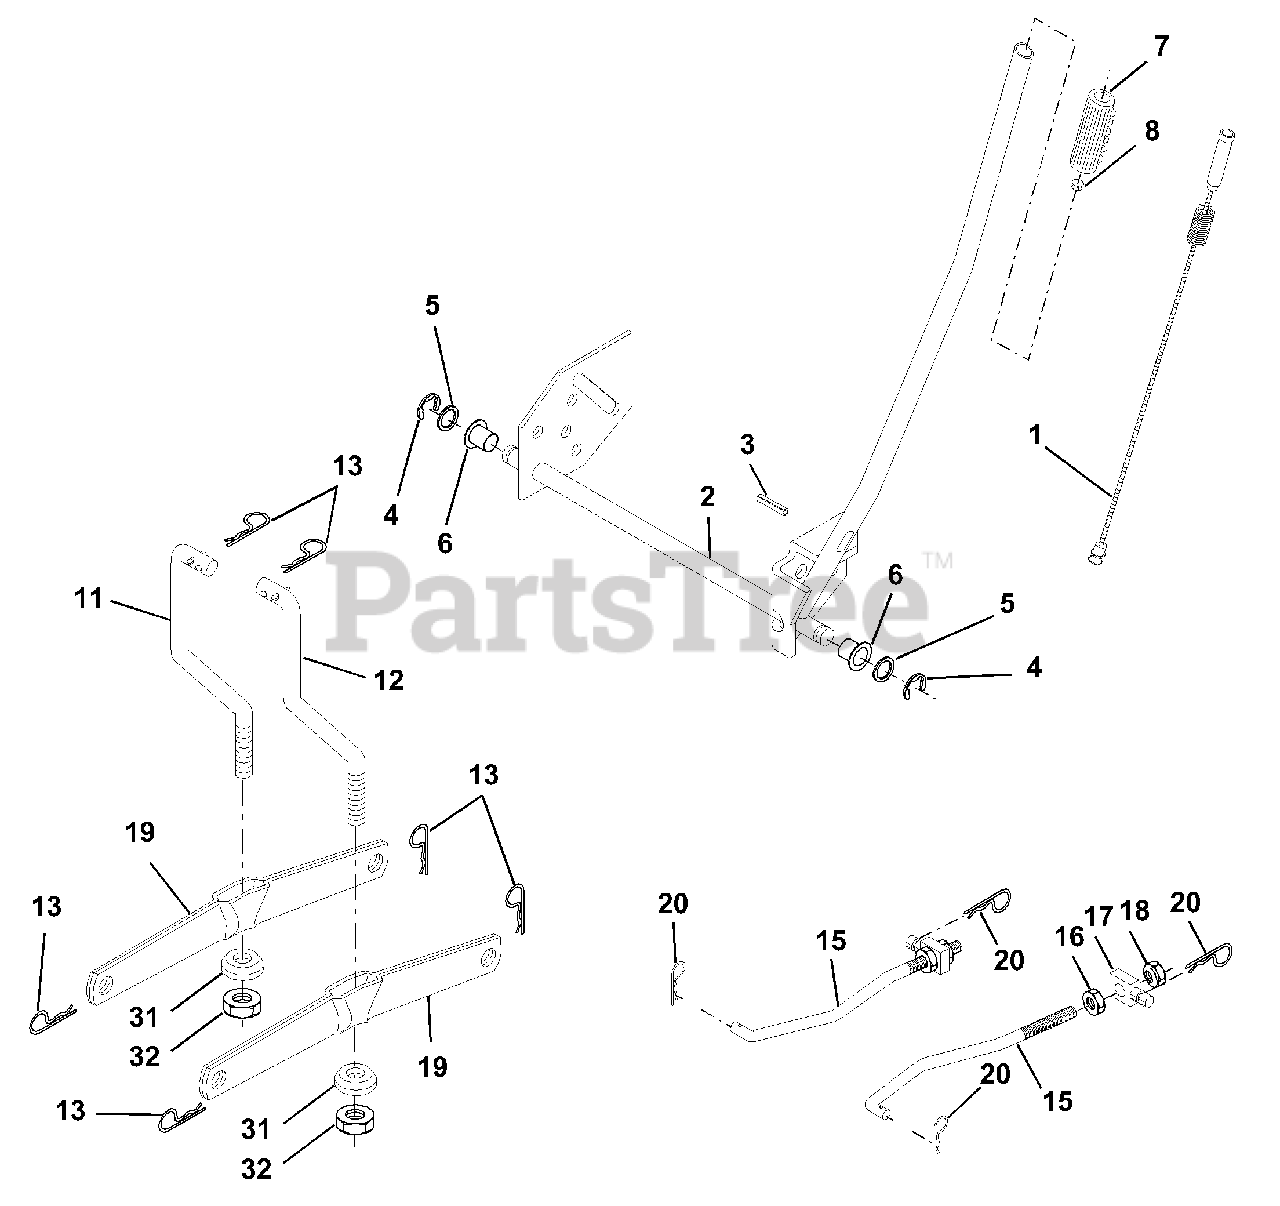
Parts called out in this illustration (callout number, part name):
1	Wire Asm Inner/Sprg w/plunger
2	Shaft Asm Lift RH
3	Pin Groove 1 500 Zinc
4	E Ring #5133-62
5	Washer 21/32 X 1 X 21 Ga
6	Bearing Nylon Blk 629 Id
7	Grip Handle Bicycle Matte Blk
8	Button Plunger Black
11	Link Lift LH Fixed Length
12	Link Lift RH Fixed Length
13	Retainer Spring
15	Link Front
16	Nut Jam Hex 1/2-13 Unc
17	Trunnion Blk Zinc
18	Nut Lockw/Wsh 1/2-13 Unc
19	Arm Suspension Rear
20	Retainer, Spring
31	Bearing Pvt Lift Spherical
32	Nut Crownlock 3/8-24
